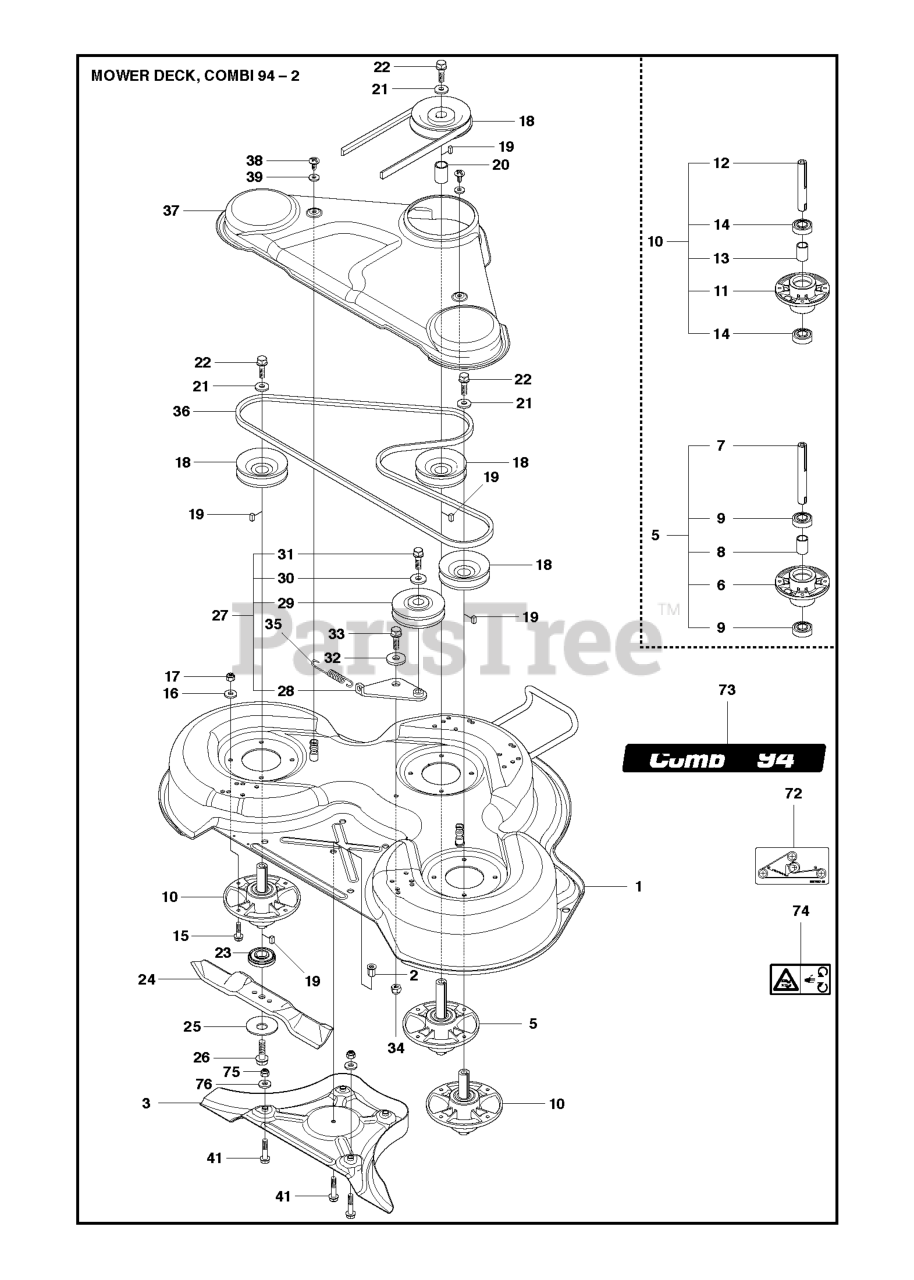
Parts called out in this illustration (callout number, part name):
3	PLUG C93 & C94
6	BEARING HOUSING
8	SPACER
9	BALL BEARING
11	BEARING HOUSING
14	BALL BEARING
16	WASHER BRB 8.4X17
17	LOCKNUT M8
25	WASHER
32	WASHER SHOULDER ASSY
32	WASHER
33	SCREW
34	LOCKNUT M8
37	BELT COVER C93 & C94 GREY
41	SCREW
41	KNOB
75	LOCKNUT M8
76	WASHER BRB 8.4X17
